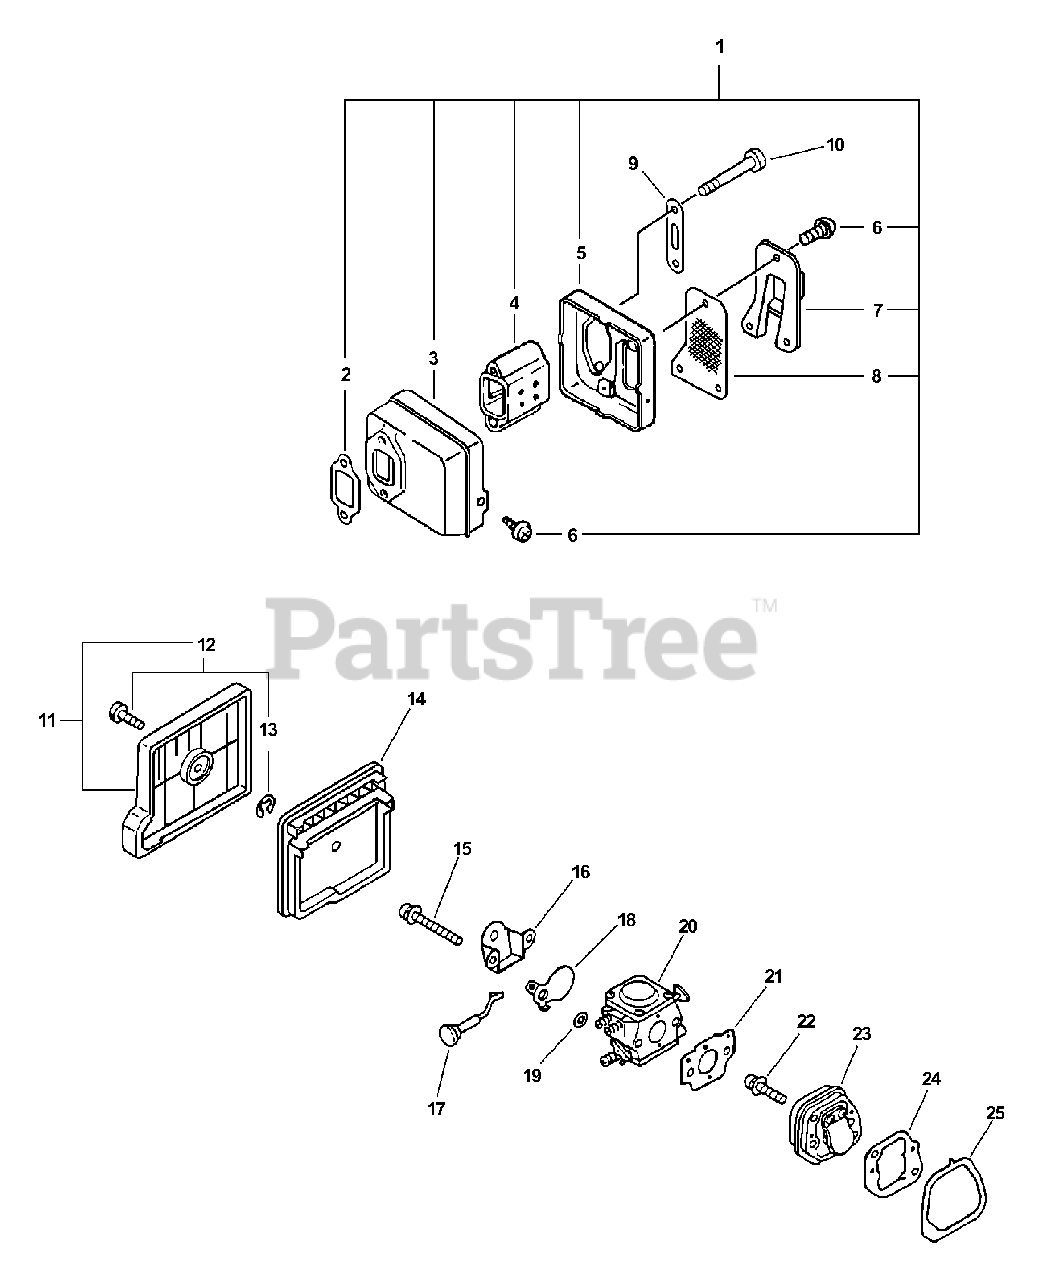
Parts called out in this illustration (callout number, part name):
1	MUFFLER ASSY
2	GASKET, EXHAUST
3	GUIDE, EXHAUST
4	BAFFLE, MUFFLER
5	GUIDE, EXHAUST
6	SCREW - 4X8
7	GUIDE, EXHAUST
8	SCREEN, SPARK ARRESTOR
9	PLATE
10	BOLT - FLANGE
11	AIR FILTER COVER ASSY
12	THUMBSCREW
13	RING, RETAINING - 4
14	FILTER, AIR
15	SCREW - 5X45
16	PLATE, PREVENT
17	ROD, CHOKE
18	SHUTTER, CHOKE
19	WASHER
20	CARBURETOR WT-385A
20	CARBURETOR WT-402A
21	GASKET, INTAKE
22	SCREW - 5X18
23	INSULATOR KIT
24	GASKET, INTAKE
25	SEAL
